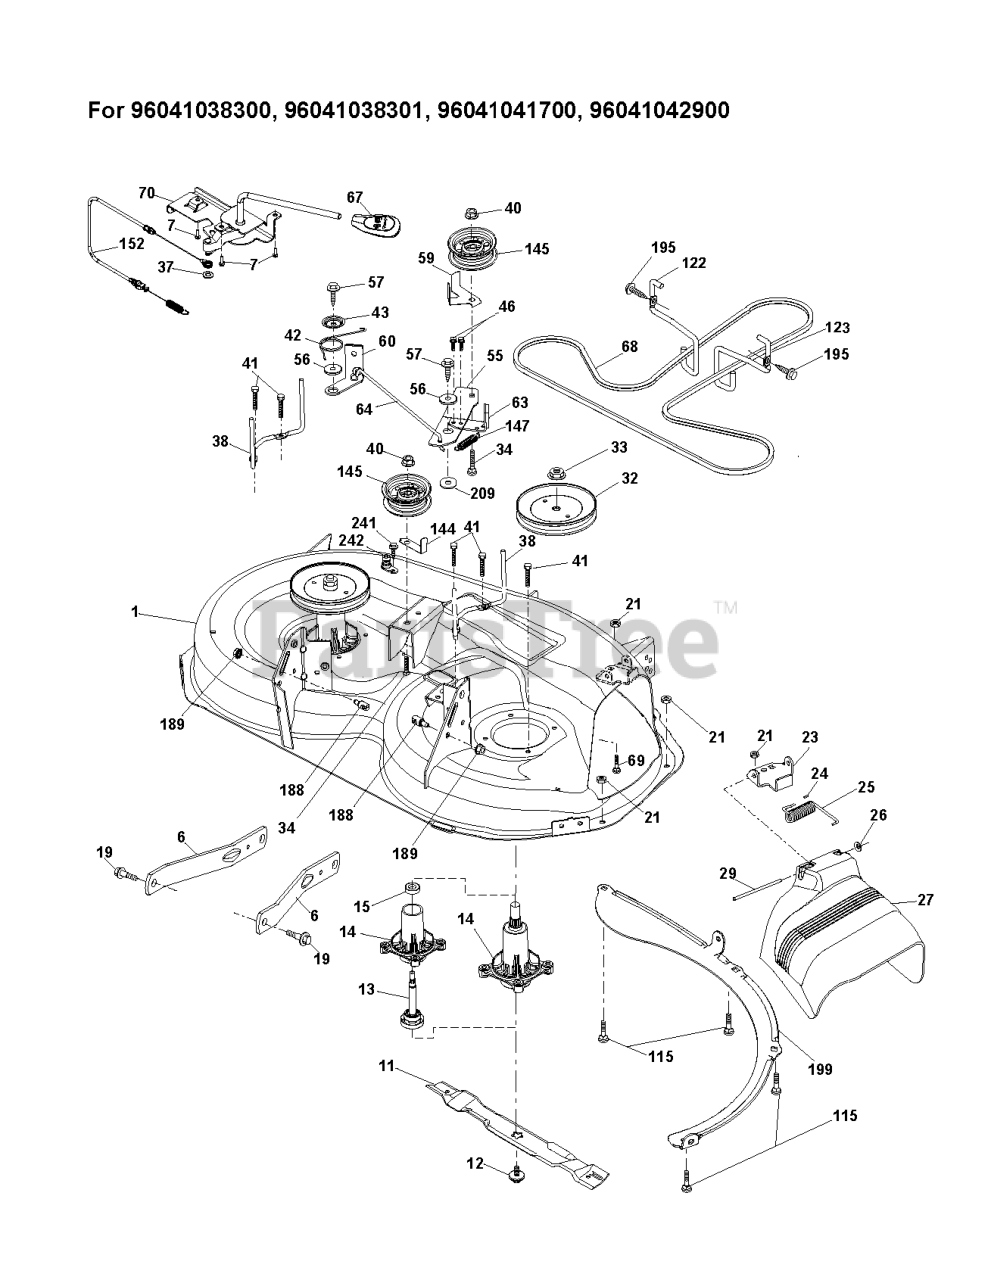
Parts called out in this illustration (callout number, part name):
1	DECK SVCX1.38"194251X418 KIT
6	ARM.SUSPENSION.MOWER.R
7	SCREW.#10 X 0.750.BOS
11	BLADE.2 IN 1.38"DECK.BLACK
12	SCREW.SEMS.7/16-20X1.HEX.HEAD
13	SHAFT ASM.MNDRL.N/GREASEABLE
14	RP.HOUSING.MANDREL.4PT.
14	KIT.MANDREL.NONGREASE.TALL
15	BEARING.MANDREL.TOP.EXTENDED
19	BOLT.SHOULDER
23	BRKT.DEFLECTOR.38"2005+
24	CAP-SLEEVE LT
25	SPRING.TORSION.DEFLECT
26	NUT PUSH M
27	SHIELD, DEFLECTOR
29	ROD.HINGE
29	Rods
32	PULLEY.MANDREL.5.0.PD.38"
34	BOLT.3/8-16X1.50
34	GSPW Bolts
37	WASHER PLAIN WASHER 3/8 X 0.08
37	WASHER
38	KEEPER BELT LH MANDREL
40	NUT LOCK FLG 3/8-16 UNC
41	BOLT.HEX.WASHR.HED.313-18X1.19
42	SPRING.TORSION.BRAKE
43	SRPING.TORSION.RETAINE
46	SCREW.1/4-20X5/8
56	SPACER.RETAINER
57	SCREW 3/8-16X1
59	GUARD, BELT
60	ARM BRAKE MOWER RH 38"
63	RP ARM.BRAKE.MOWER.38"LH.TEX
64	LINK BRAKE
67	HANDLE.CLUTCH.CABLE.LT
69	BOLT
70	CLUTCH.ASM.MANUAL.LT.PRED
115	BOLT ROUND HEAD SQUARE NECK BO
115	BOLT.CARR.5/16-18X5/8.SHORT
122	KEEPER BELT ENGINE LH
123	KEEPER BELT RH
144	KEEPER BELT
145	PULLEY.IDLER.48"PRIMARY
147	SPRING RETURN
152	CABLE.CLUTCH.MANUAL.
188	STUD.FASTNER.W/ANTI-ROTATE
188	STUD.W/"D"ANTI-ROTATION
189	NUT LOCK HEX FLANGE 5/16-18
195	SCREW, 3/8-16X3/4
199	BAFFLE.VORTEX.FRONT.38"
241	SCREW.TT.#10-32X.5.3/8.FLANGE
242	PORT.WASHOUT
